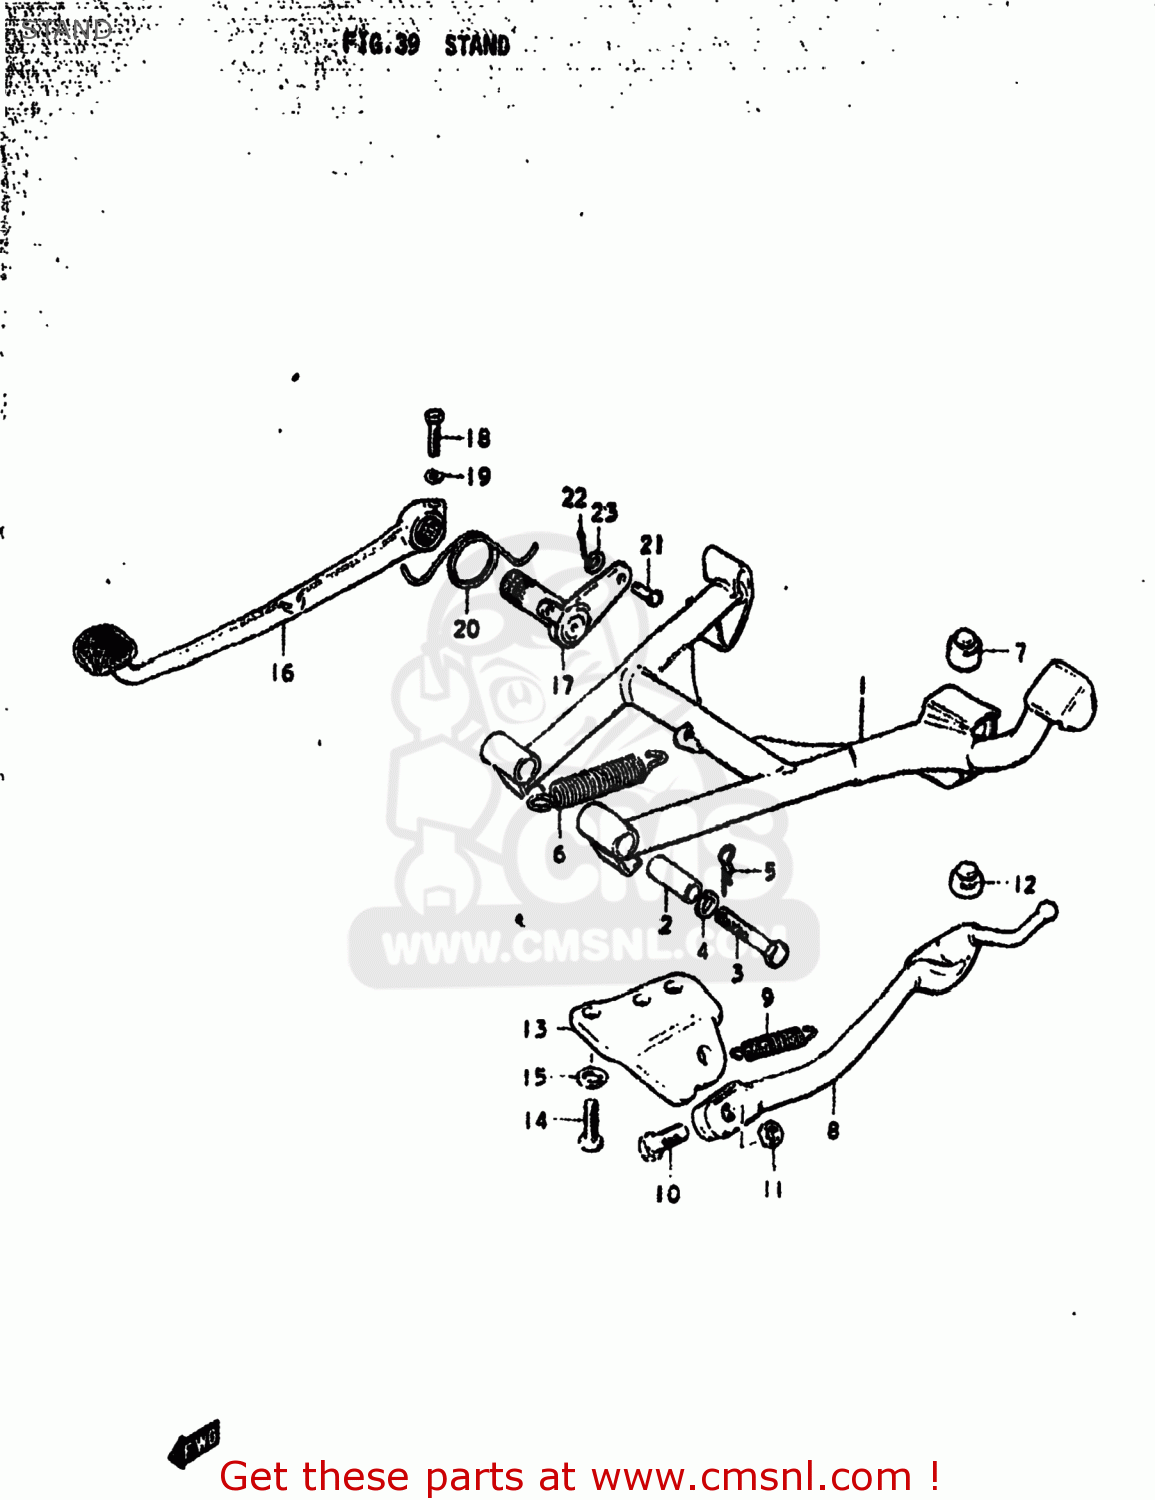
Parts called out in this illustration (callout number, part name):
1	STAND,CENTER
2	SPACER(10X16X38.8)
3	BOLT
4	LOCK WASHER
5	CLIP
6	SPRING
7	CUSHION
8	STAND,PROP
9	SPRING
10	BOLT(10X30)
11	NUT
12	CUSHION(11.5X22X20)
13	BRACKET,SIDE STAND
14	BOLT
15	LOCK WASHER
16	PEDAL,BRAKE
17	ARM,BRAKE PEDAL ROD
18	BOLT
19	LOCK WASHER
20	SPRING
21	PIN
22	COTTER PIN
23	WASHER
